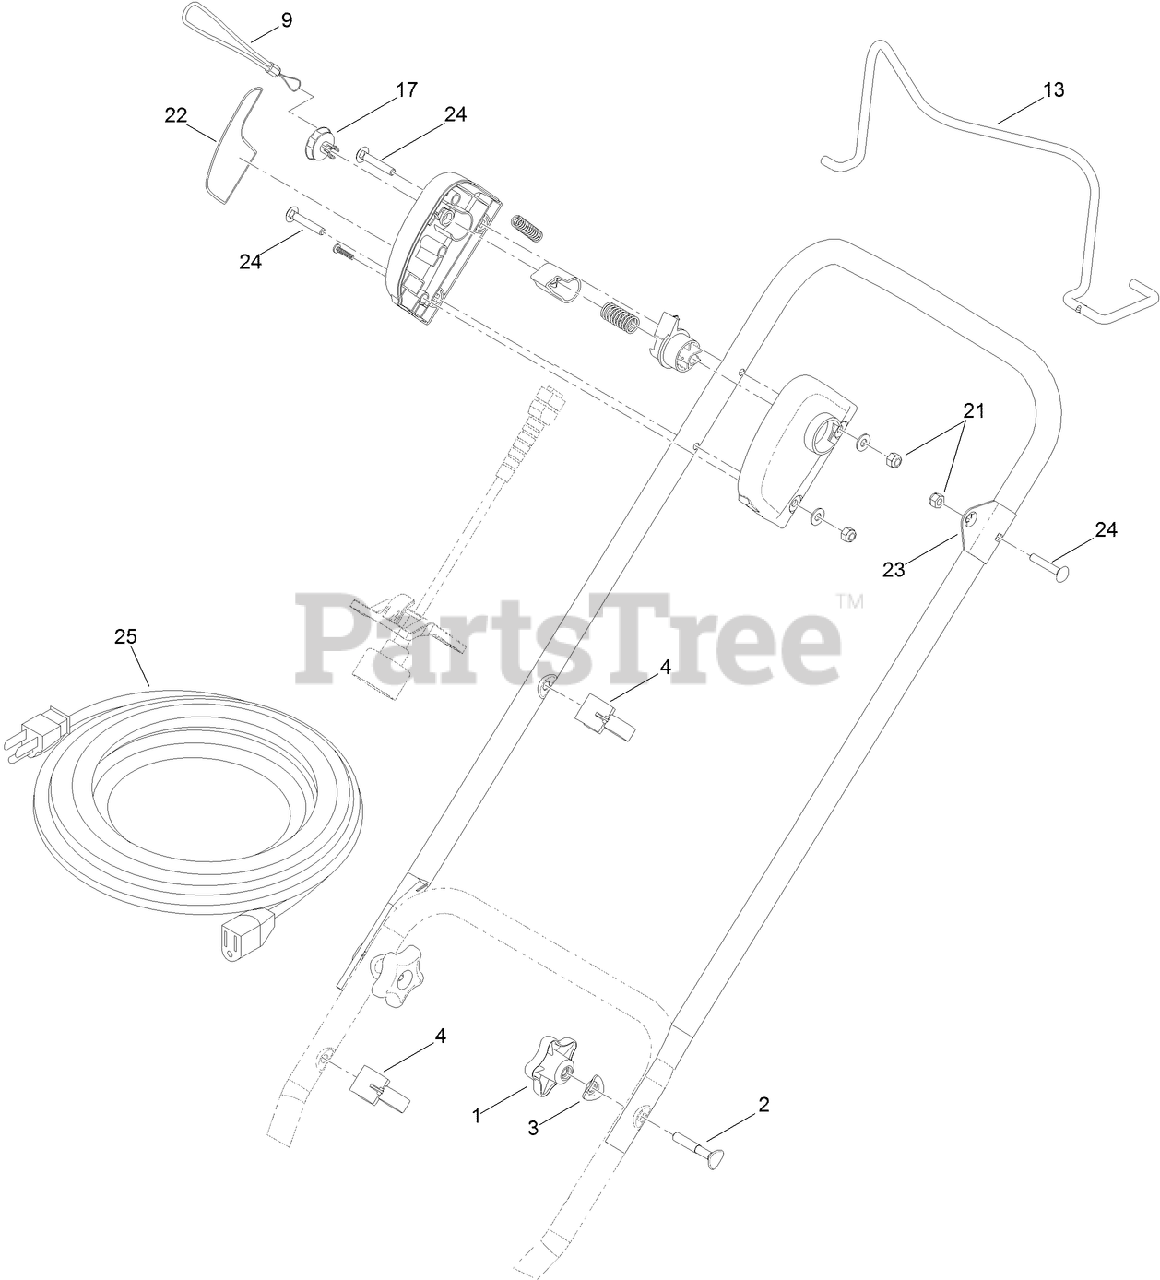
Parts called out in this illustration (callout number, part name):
1	KNOB-HANDLE
4	GUIDE-CABLE
21	NUT-LOCK, NI
22	DECAL-OPERATION
23	BRACKET-BAIL
24	SCREW-CARR
25	CORD-EXTENSION, COLD WEATHER
